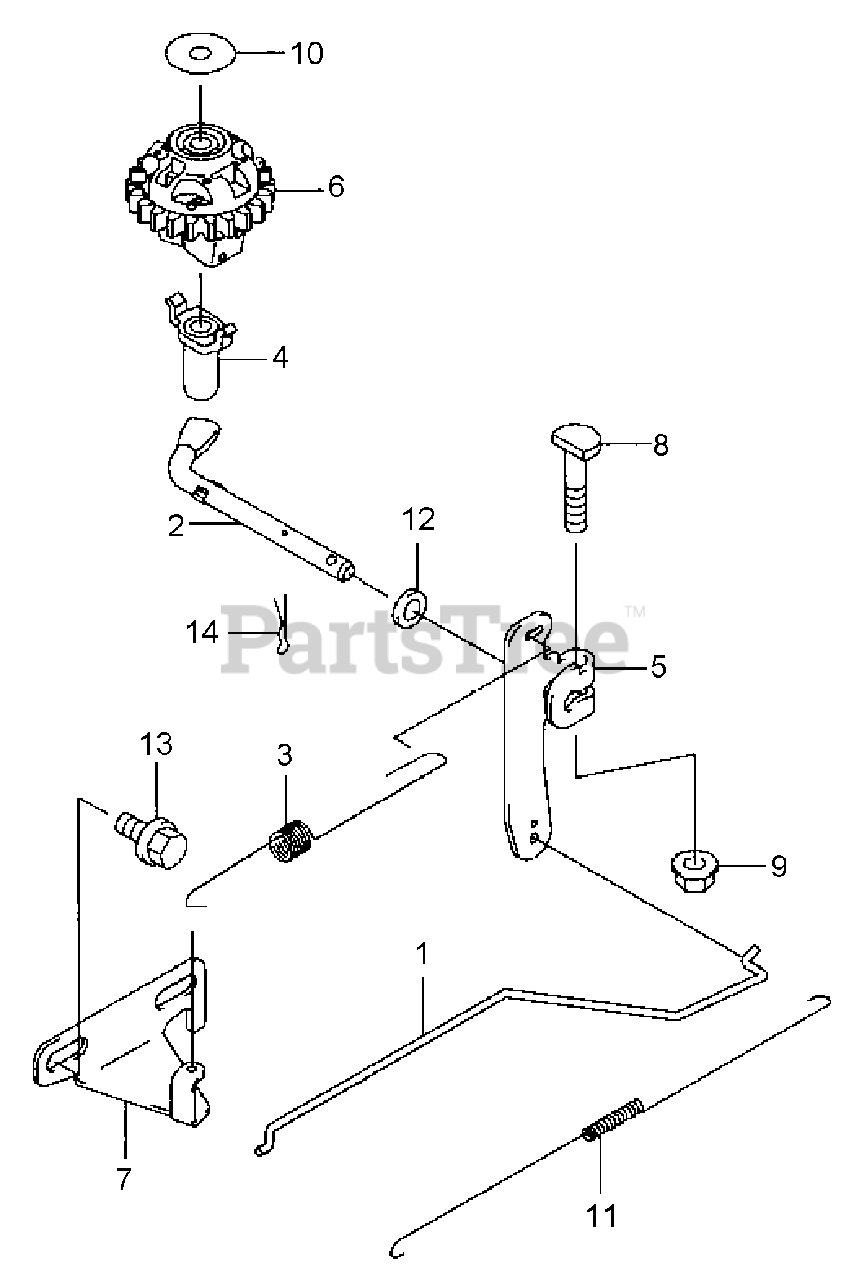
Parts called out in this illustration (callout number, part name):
1	Throttle Link
3	Governor Spring
6	Governor Assy.
7	Control Panel
9	Nut
11	Throttle Spring
12	Washer, 6.5x11.5x2.0
13	Flanged Bolt
